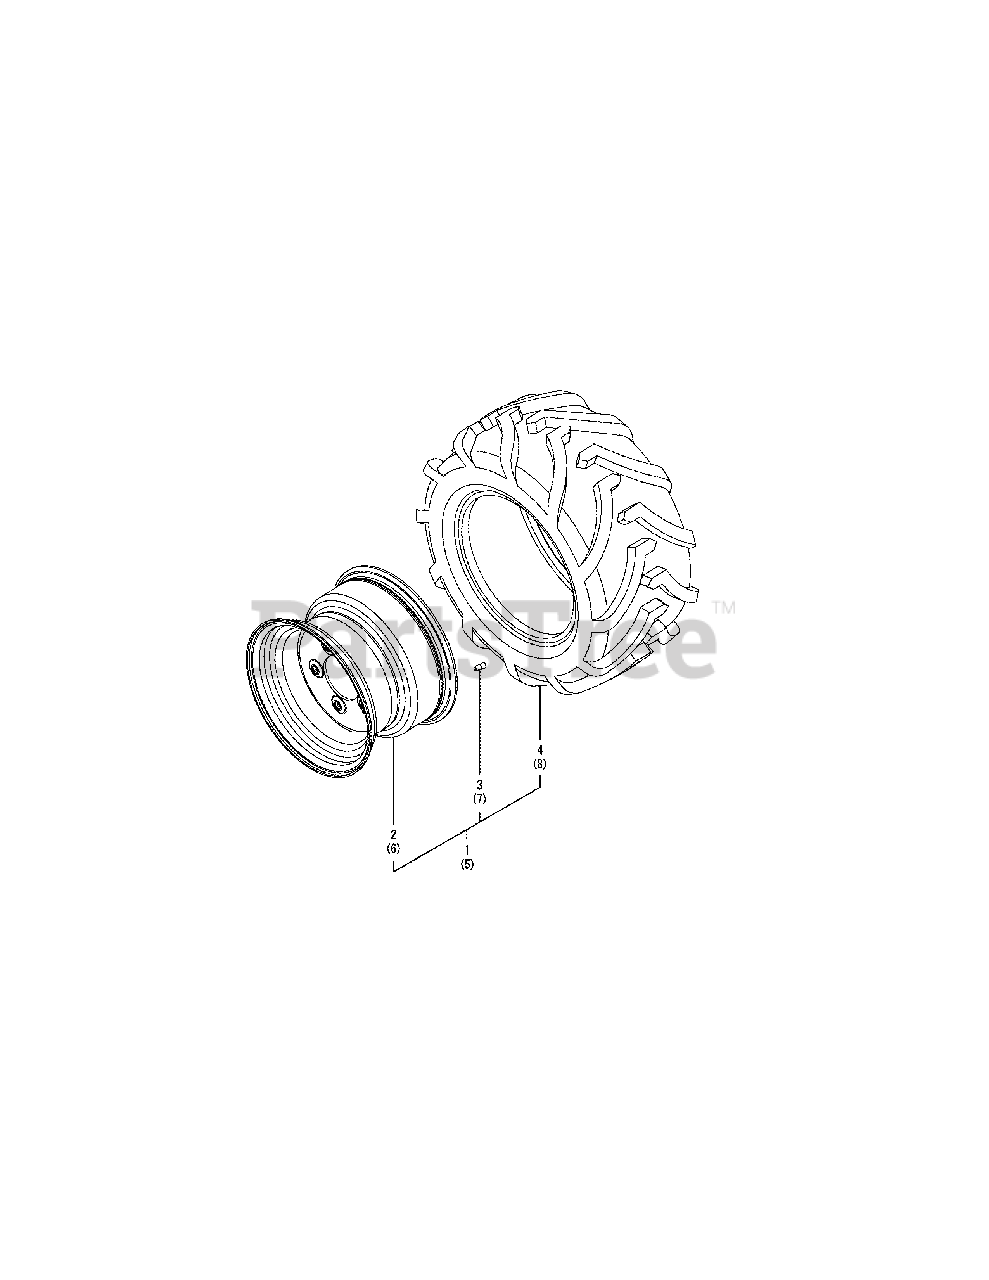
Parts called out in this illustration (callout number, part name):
1	R1 FRONT TIRE L KIT
4	TIRE,18X8.5-10 R1
5	R1 FRONT TIRE R KIT
8	TIRE,18X8.5-10 R1
